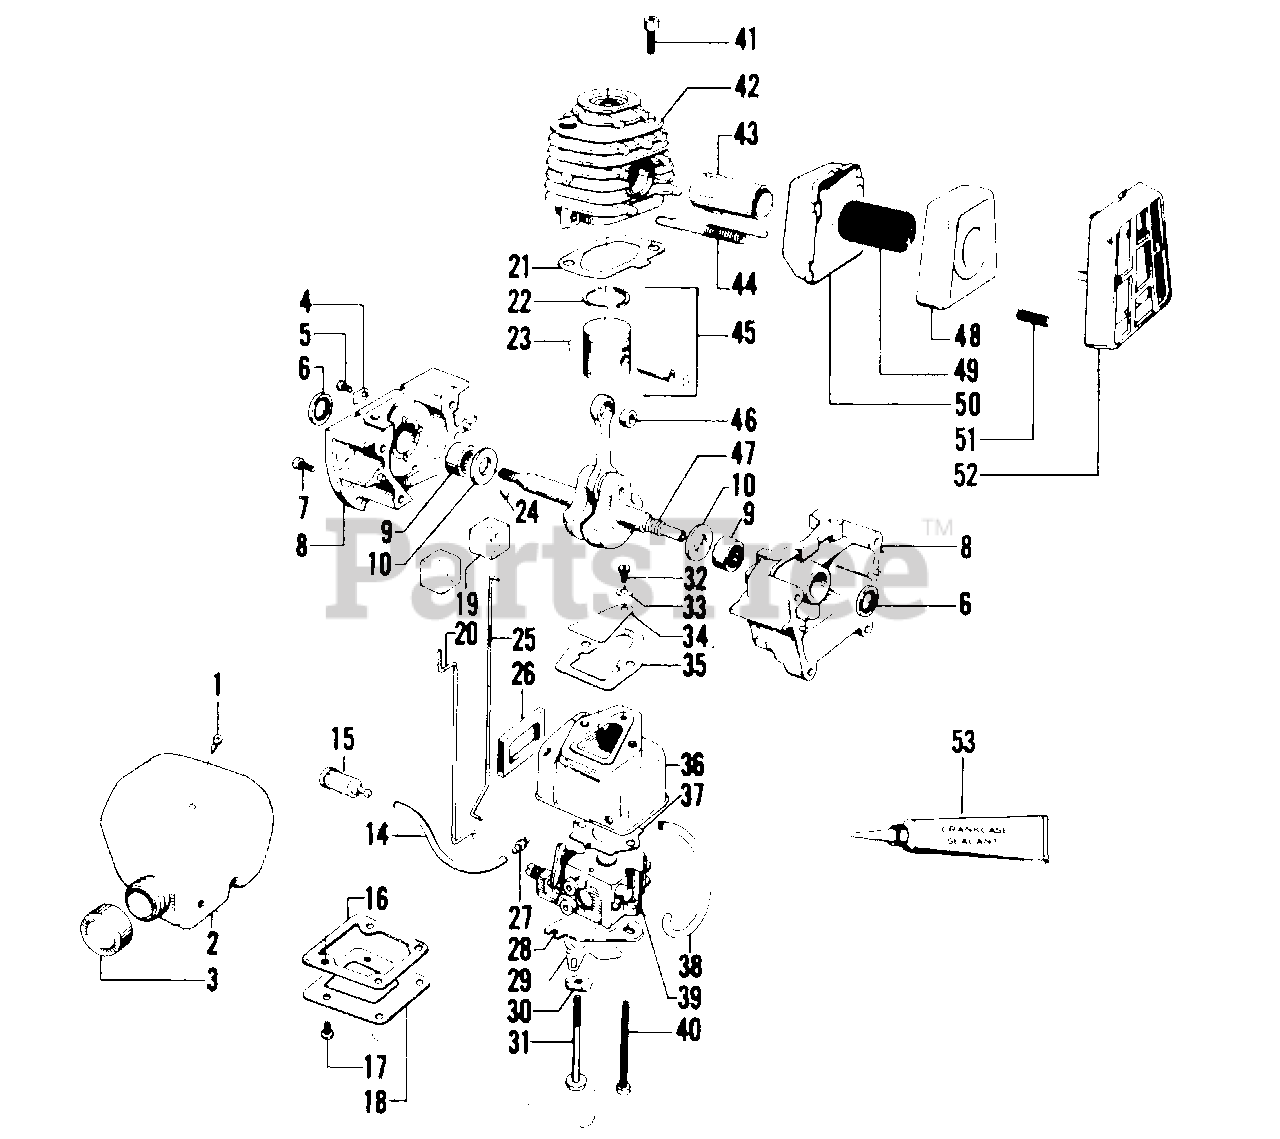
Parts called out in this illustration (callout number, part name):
1	Check Valve - Duck Bill
2	Fuel Tank Assembly (Inc.1,3,14,15)
3	Fuel Cap Assembly
4	Clamp - Choke Wire
5	Screw - #8 - 32 x 5/16" - Pan Hd. - Choke Rod Clamp
6	Seal - Crankcase
7	Screw - Crankcase - #10 - 24 x 5/8"
8	Crankcase Assembly (Inc.4, 9 4 Qty. 4 of #7)
9	Bearing - Crankcase
10	Washer - Thrust - Crankcase
14	Fuel Line
15	Fuel Pick-up Ass'y
16	Gasket - Carburetor Case Cover
17	Screw - #8 - 18 x 9/16" - Pan Hd. - Carburetor Case Cover
19	Boot - Throttle - Choke Wire
21	Gasket - Cylinder
22	Ring - Piston
23	Retainer - Wrist Pin
24	Key - Flywheel
25	Throttle Wire
26	Seal - Carburetor Case
27	Fuel Line Fitting
29	Choke Shutter
30	Washer - Wave
31	Screw - #10 - 24 x 2-1/8" - Fil. Hd. - Carburetor Shoulder
32	Screw - #6 - 19 x 5/16" - Pan Hd - Reed Valve
33	Washer - Reed Valve Screw
34	Reed Valve
35	Gakset - Carburetor Case to Crankcase
36	Carburetor Housing
37	Gasket - Carburetor
38	Fuel Line Carburetor
39	Carburetor - See Service Ref. 2.
40	Screw - #10 - 24 x 1-7/8" - Fil. Hd. - Carburetor
41	Screw - #1/4 - 20 x 3/4" - Hex Socket Hd. Cylinder
42	Cylinder
43	Diffuser - Muffler
44	Spring - Muffler Detachment
45	Piston Assembly (Inc.22,23,Pin)
46	Bearing - Wrist Pin
47	Crankshaft & Rod Assembly
48	Cover - Muffler
49	Screen - Spark Arresting
50	Body - Muffler
51	Spring - Muffler Guard
52	Guard - Muffler
53	Sealant - Crankcase (Not Supplied with Unit)
